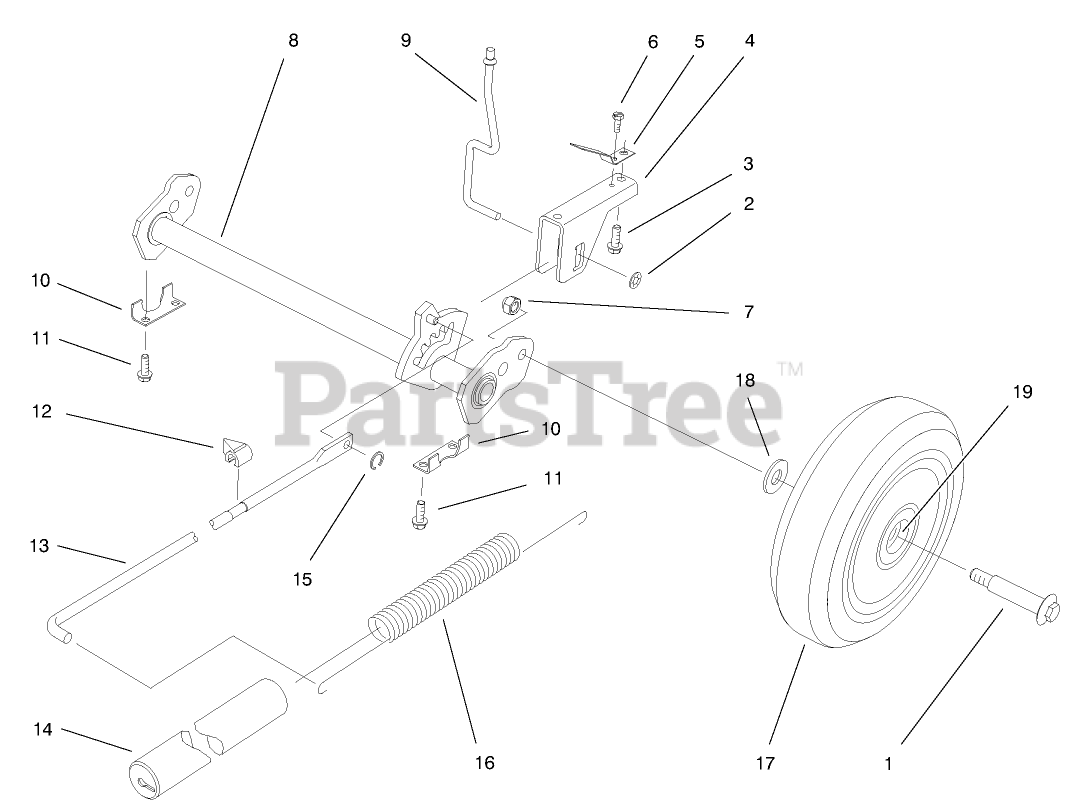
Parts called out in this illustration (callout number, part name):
1	BOLT-WHEEL
2	PUSHNUT
3	SCREW
4	SADDLE - HOC
6	SCREW 8 - 32 X 250
7	NUT-HEX
8	PIVOT ARM REAR WA
9	TRIGGER ROD
11	SCREW-HWH
12	INDICATOR-HEIGHT OF CUT
13	LINK ROD
14	COVER-SPRING
15	GRIP RING
16	SPRING-COUNTERBALANCE
18	WASHER
19	BUSHING
